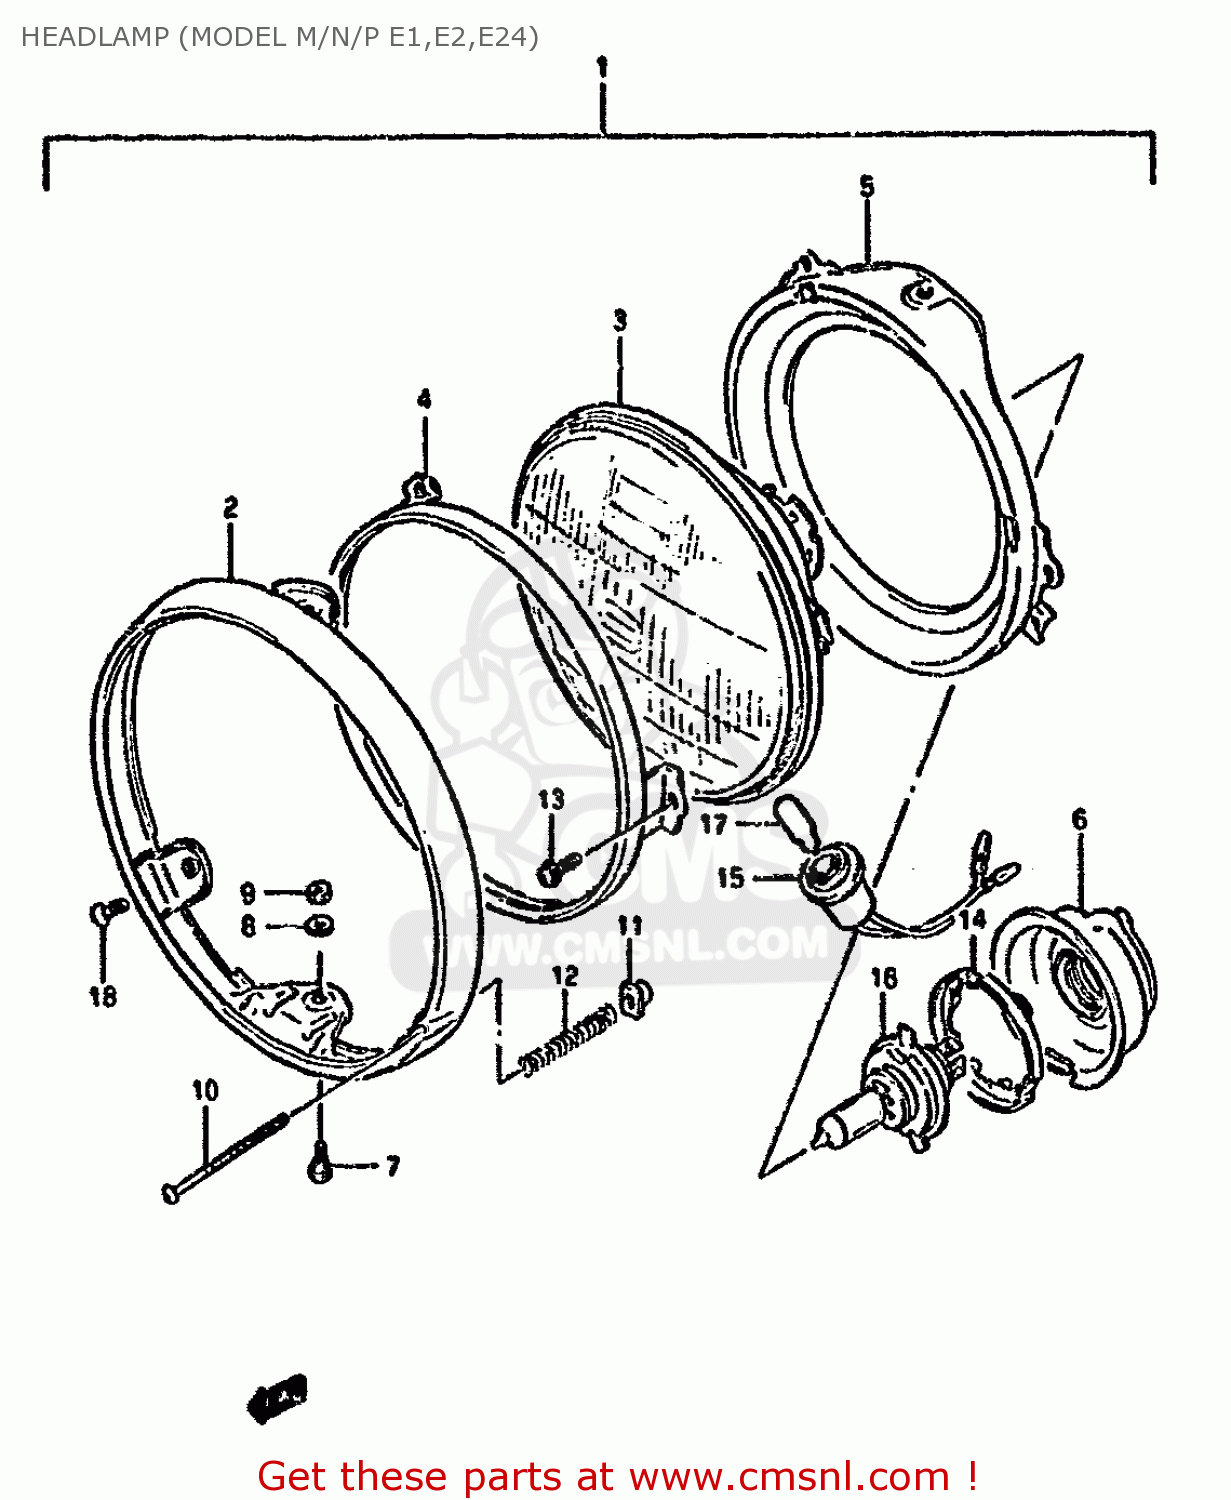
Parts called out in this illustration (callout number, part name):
1	HEADLAMP ASSY
2	RIM,HEADLAMP
3	LAMP UNIT
4	RETAINING RING
5	RING
6	COVER,HEADLAMP SOCKET
7	H/LAMP LENS UNIT FITING SCRE
8	WASHER,LOCK
9	NUT
10	SCREW,HEADLAMP ADJUST
11	NUT
12	SPRING,ADJUSTING
13	SCREWM4X0.7X10
14	SETTING,BULB
15	SOCKET
16	BULB(12V60/55W,H4)
17	BULB(12V4W)
18	SCREW
